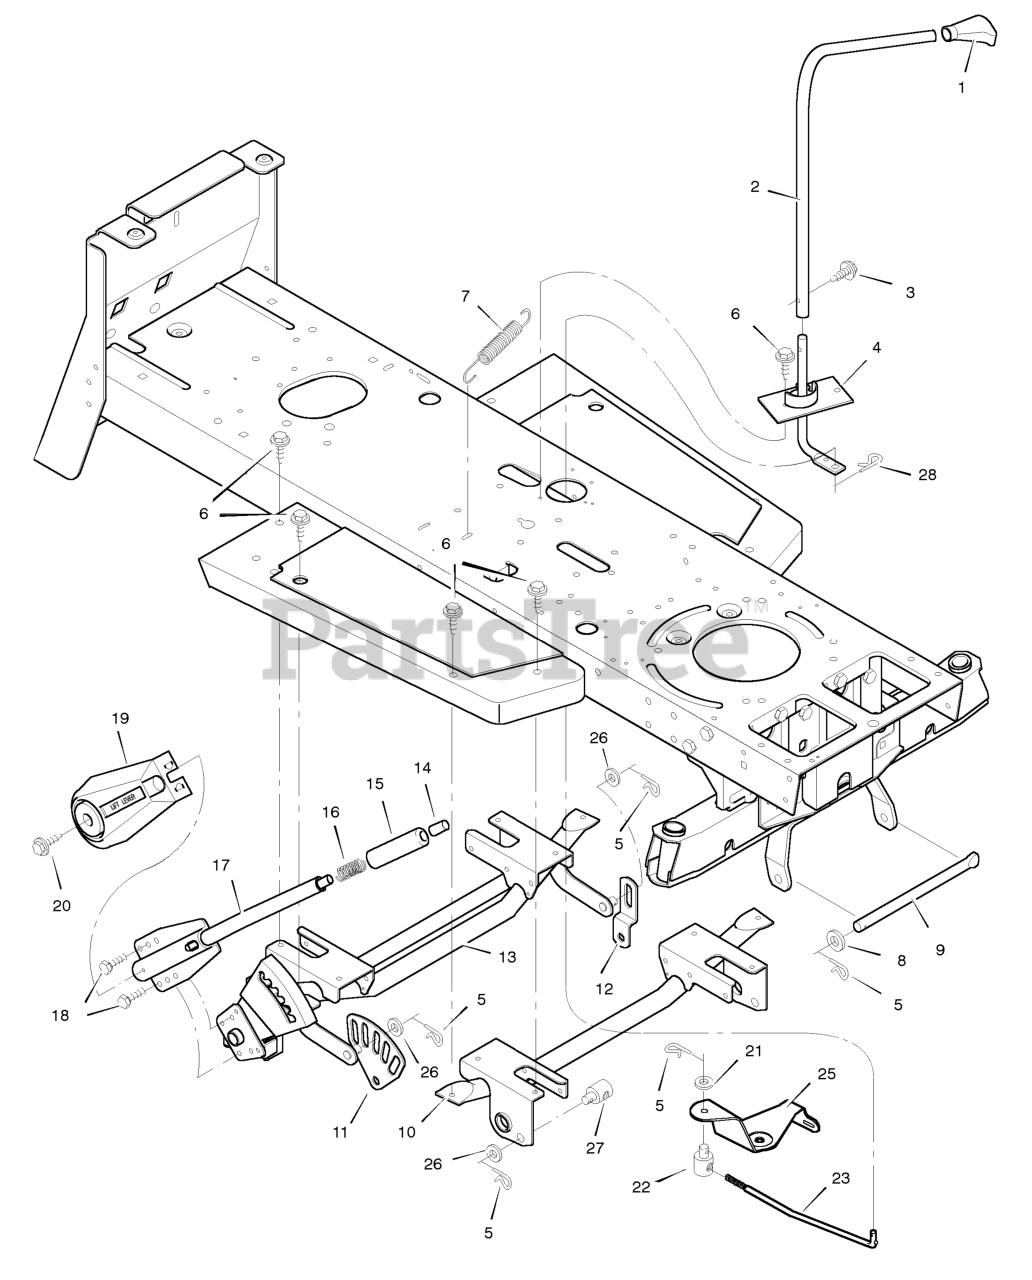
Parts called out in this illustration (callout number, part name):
1	Grip
2	Lever, Blade Control
3	Screw, Hex
4	Control Assembly, Blade
5	Pin, Hair
7	Spring, Extension
9	Pin, Pull
10	Support Assembly, Front
11	Plate, Adjuster
12	Link, Suspension
13	Support, Lifter
14	Button, Push
16	Spring, Compression
17	Handle Assembly
19	Cover, Lift Lever
22	Nut, Adjusting
23	Link, PTO
24	Washer
25	Bracket, Pivot
27	NUT, Adjusting, 1/2-13
28	Pin, Hair
